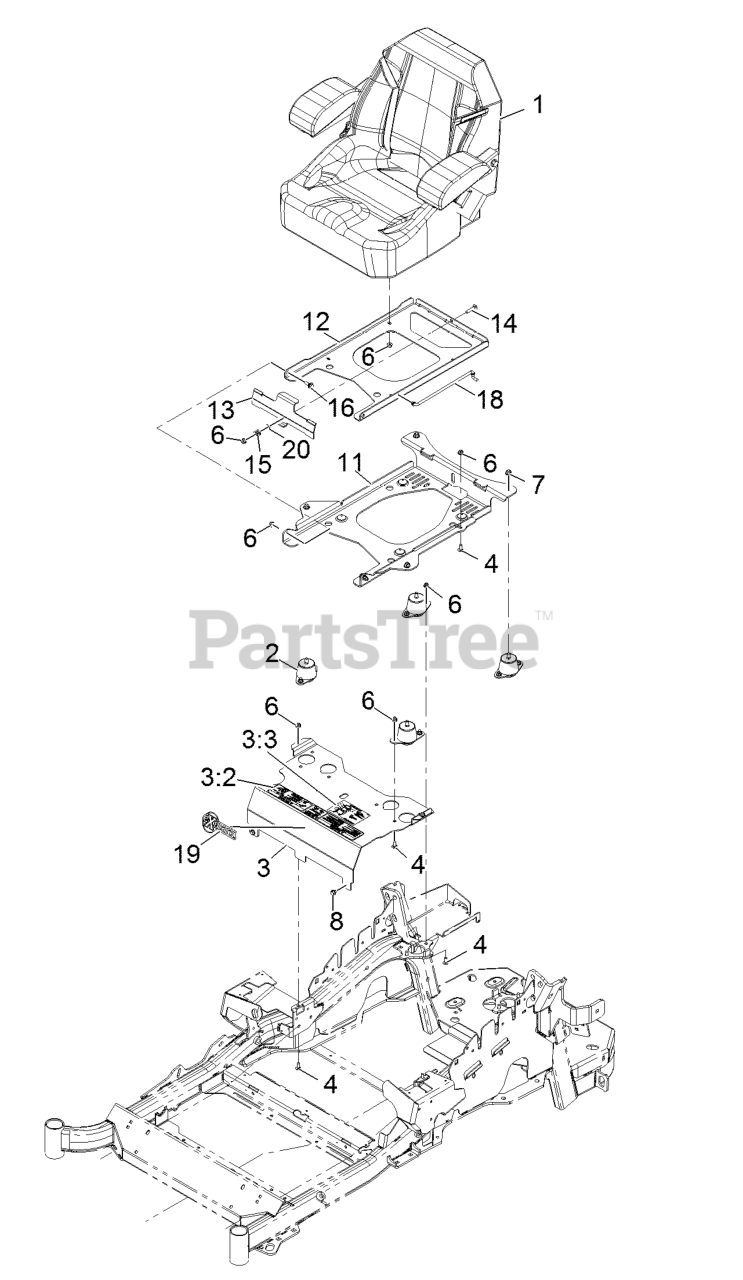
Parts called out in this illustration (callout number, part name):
2	ISOLATOR-SEAT
3	MOUNT-SEAT
3:2	DECAL-CONSOLE
3:3	DECAL-SERVICE AID
4	SCREW-CARR
6	NUT-HF, NI
7	NUT-HF, NI
11	PLATE-TILT, SEAT SUPPORT
12	PLATE-FRAME, SEAT
13	PLATE-LATCH, SEAT
14	BOLT-CARR
15	SPRING-COMPRESSION
16	SCREW-SHOULDER
18	ROD-PROP
20	WASHER-PLAIN
